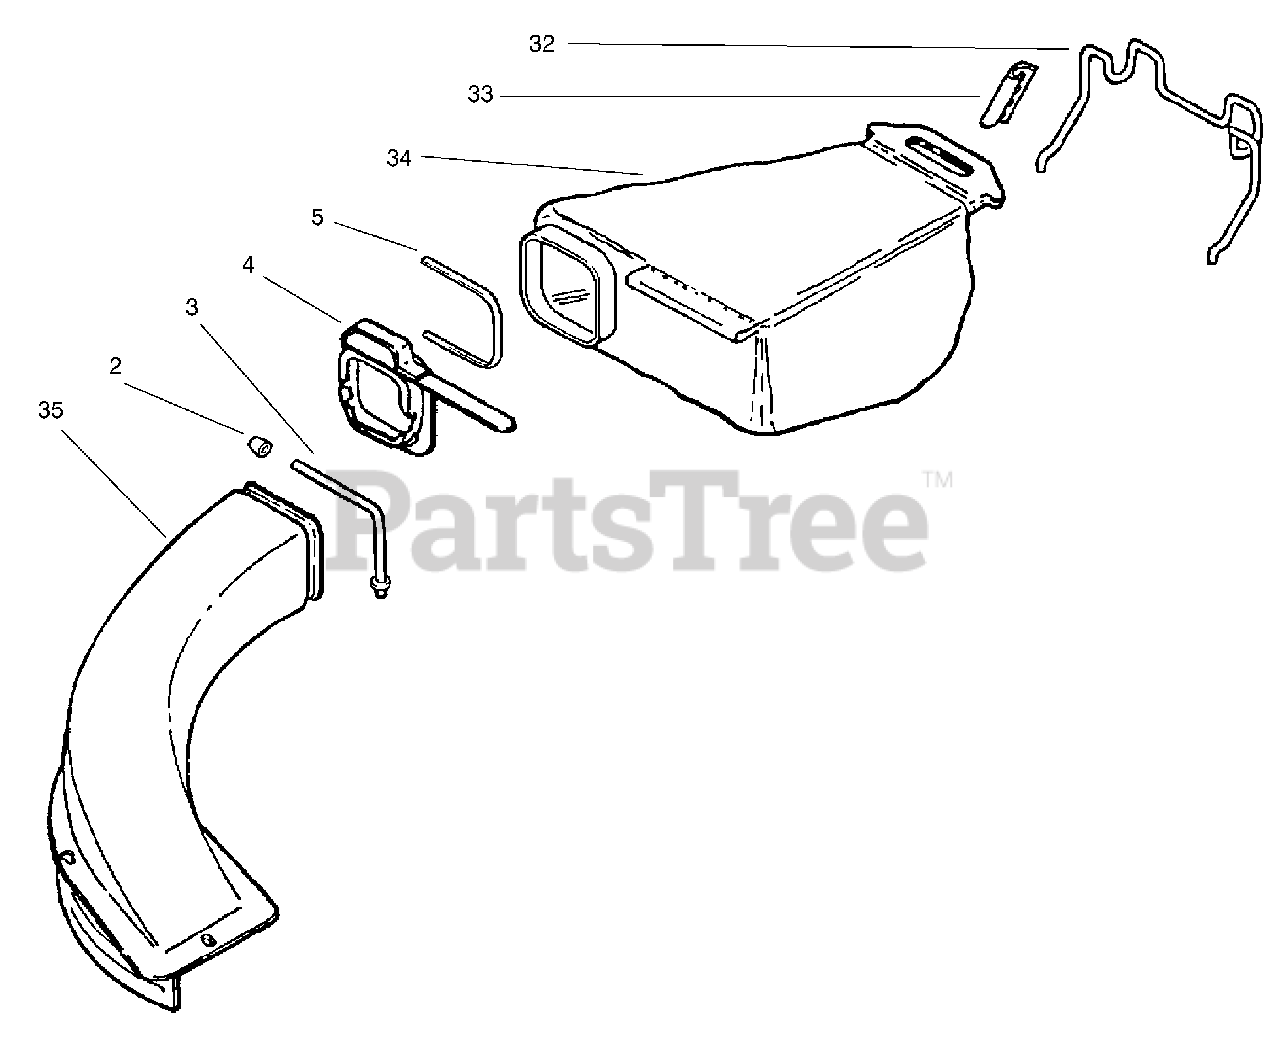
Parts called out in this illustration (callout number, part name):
2	Nut-Cap
3	Support-Chute
4	ASM-Adapter
5	Tie Strap
32	Wire Hanger,
33	Clamp-Hanger
34	Bag & Adapter ASM.
35	Chute & Support
